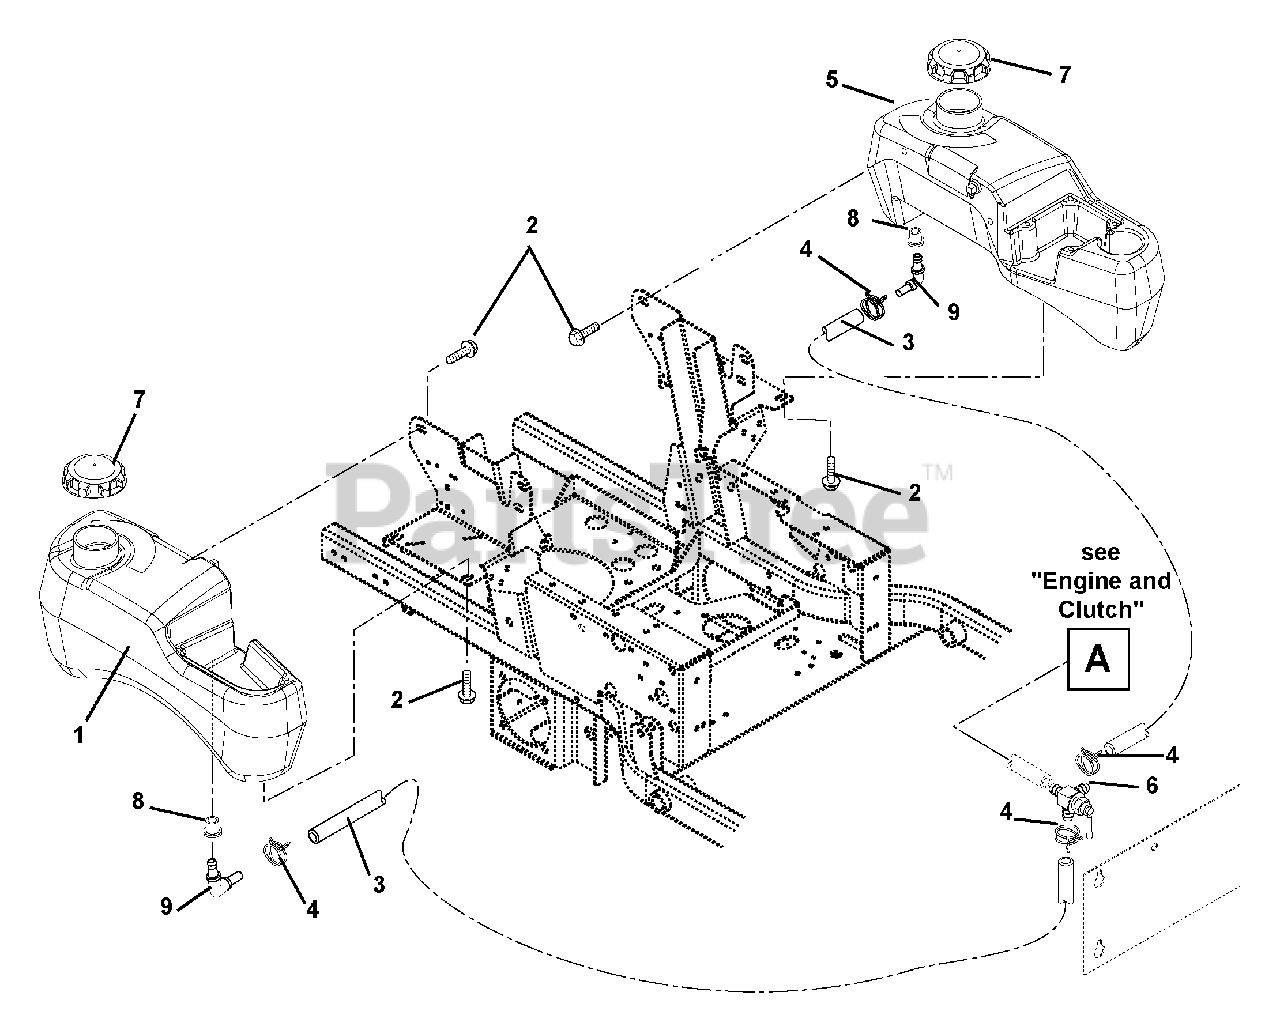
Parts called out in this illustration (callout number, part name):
1	TANK, GAS - RH W/O HOSE
2	BOLT, SEMS .31-18 X .62
3	GAS LINE-BULK 1/4" I.D.
4	CLAMP-HOSE WIRE .490/.510X.116
5	TANK, LH FUEL 100 S. W/O HOSE
6	VALVE, FUEL
7	CAP - FUEL
8	BSHG-FLG .375 X 1.062 X .625 R
9	FITTING, TANK ELBOW .25 HOSE
